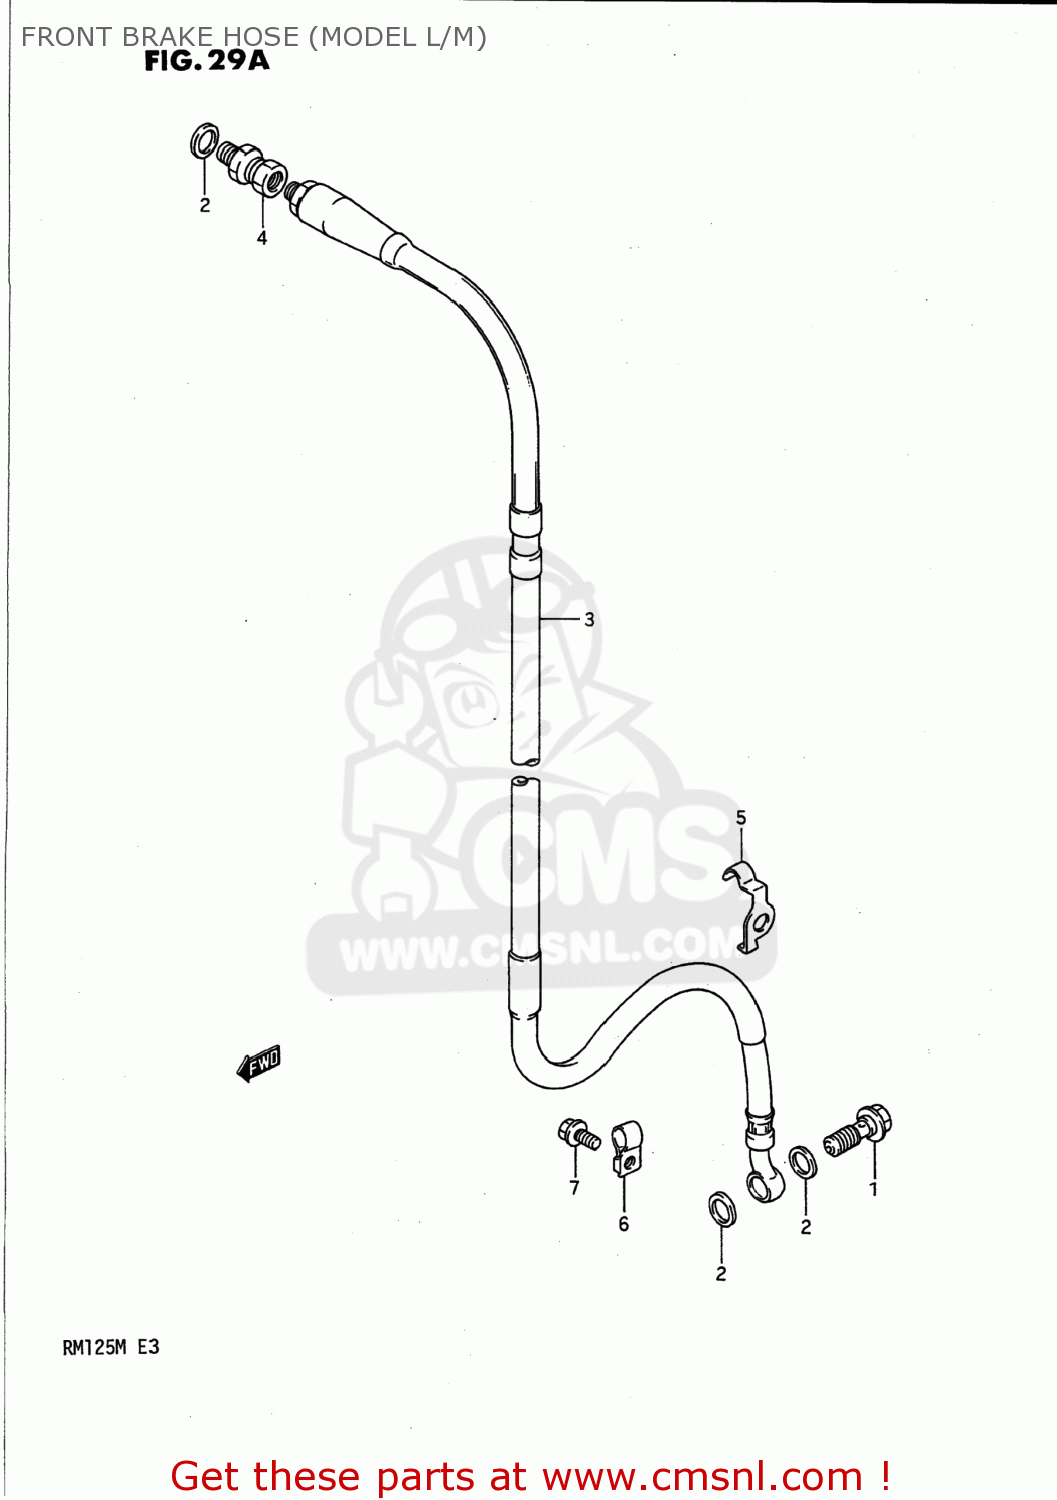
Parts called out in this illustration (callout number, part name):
1	BOLT UNION
2	WASHER(10X15X1.5)
3	HOSE,FRONT BRAKE
4	ADAPTOR,BRAKE HOSE
5	CLAMP,FRONT BRAKE HOSE
6	CLAMP,FR BRAKE HOSE NO.2
7	BOLT
